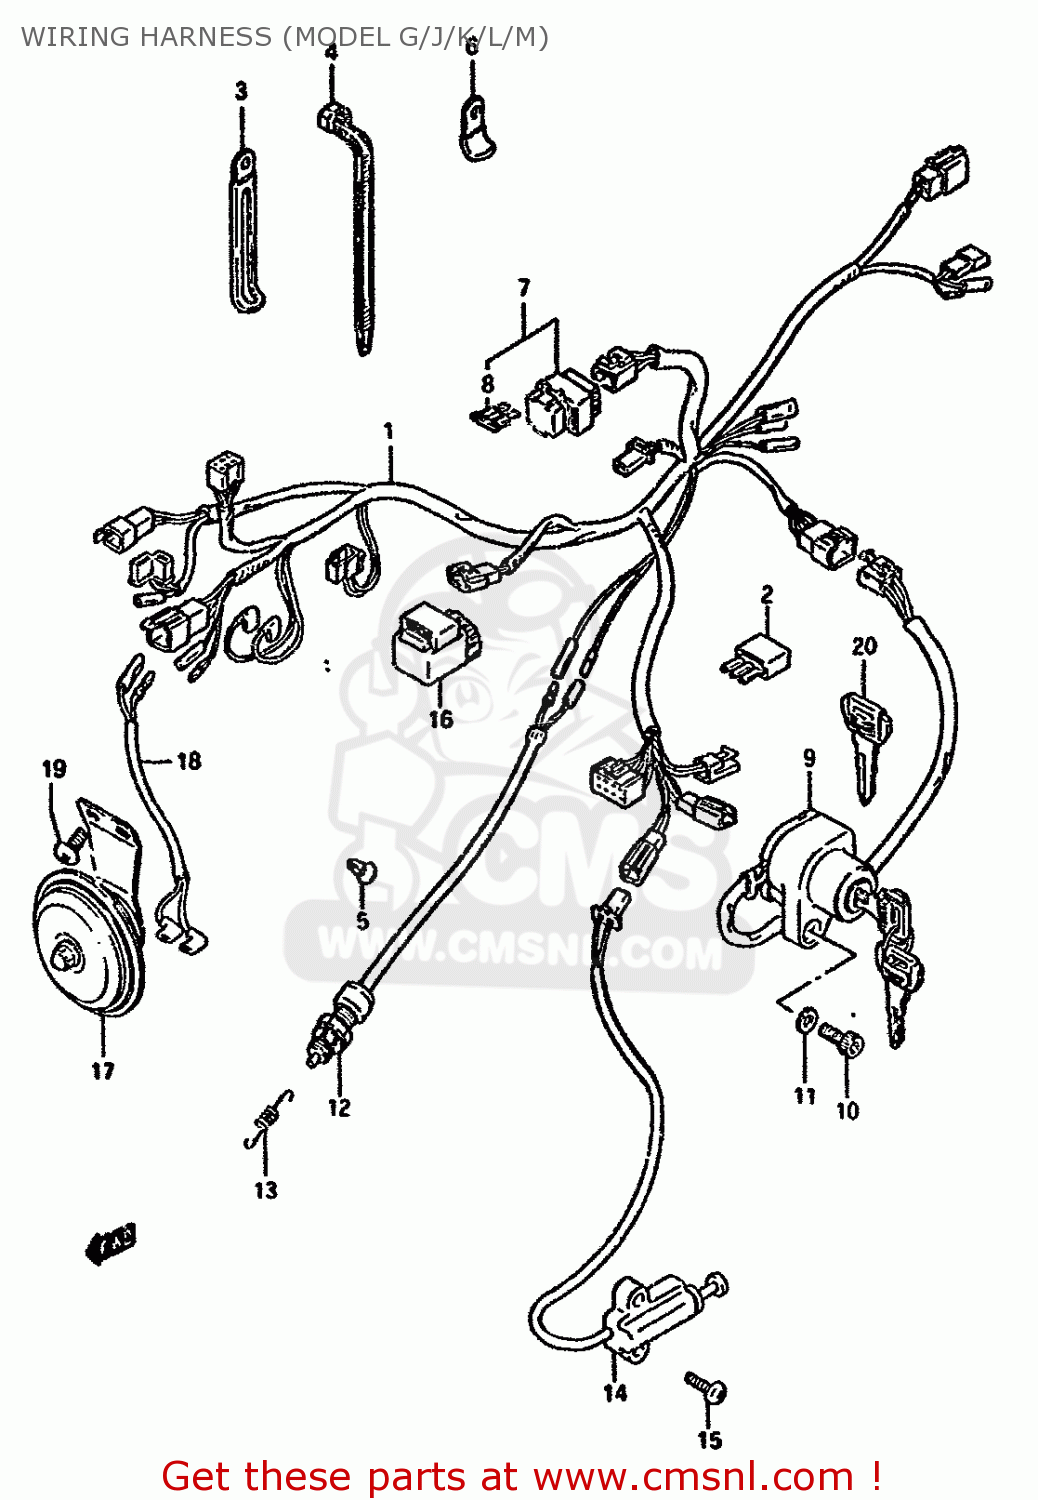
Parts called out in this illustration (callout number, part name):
1	HARNESS,WIRING
2	DIODE(STANLEY DE8804)
3	CLAMP
4	CLAMP(L:125)
5	CLIP
6	CLAMP
7	BOX ASSY,FUSE
8	FUSE(20A)
9	SWITCH ASSEMBLY,IGNITION
10	BOLT
11	WASHER,LOCK
12	SWITCH ASSY,STOP LAMP
13	SPRING
14	SWITCH ASSEMBLY,SIDE STAND
15	BOLT
16	RELAY ASSEMBLY
17	HORN ASSY
18	WIRE,HORN LEAD
19	SCREW
20	WASHER,LOCK
21	RELAY ASSEMBLY
22	HORN ASSY
23	HORN ASSY
24	WIRE,HORN LEAD
25	SCREW 6X12
26	KEY,BLANK(TYPE:C)
